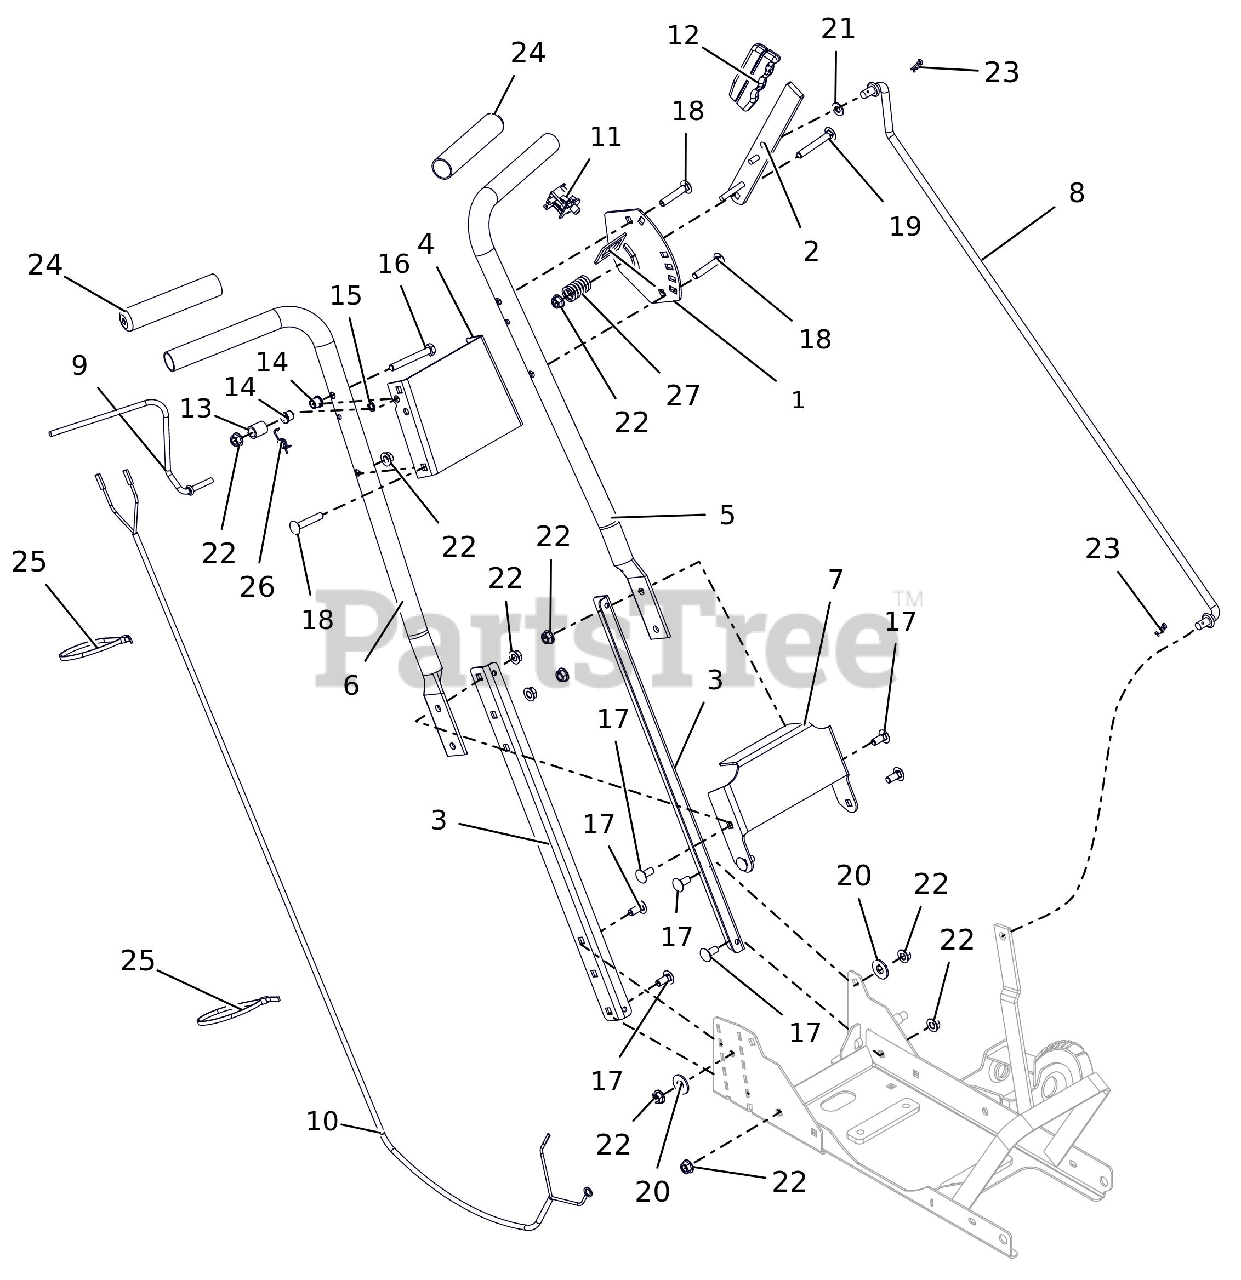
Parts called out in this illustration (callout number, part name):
1	DETENT,PIVOT
2	LEVER,PIVOT
4	PANEL,UPPER
5	HANDLEBAR,UPPER LH
6	HANDLEBAR,UPPER RH
7	PANEL,LOWER
8	ROD, PIVOT
9	ROD, OPC
10	HARNESS, EDGER
11	SWITCH- SNAP MTG N.C.
12	GRIP, PARKING BRAKE (YELLOW)
13	SPACER, GROUND .462X.625X.750
14	BSHG-FLG .325X.444X.440X.560
15	RG-RTNG-EXT .250X.010
16	@BLT-HEX .31-18X2.50 GR5 YWZC
17	@BLT-RDHDSQNK .31-18X.75 G5YZ
18	@BLT-RDHDSQNK .31-18X1.75 G5YZ
19	@BLT-RDHDSQNK .31-18X2.25 G5YZ
20	@WSHR-FL-STL.438X1.00X.083 YWZ
21	@WSHR-FL-STL.344X.688X.065YWZC
22	@NUT-LK-TOP-FLG .31-18 YWZC
23	PIN-HAIR, ENDRIES #25 YWZC
24	HANDLE GRIP
25	CABLE TIE LG 5-1/2
26	SPRING, TORSION
27	SG-COMP .125X.781X1.250
